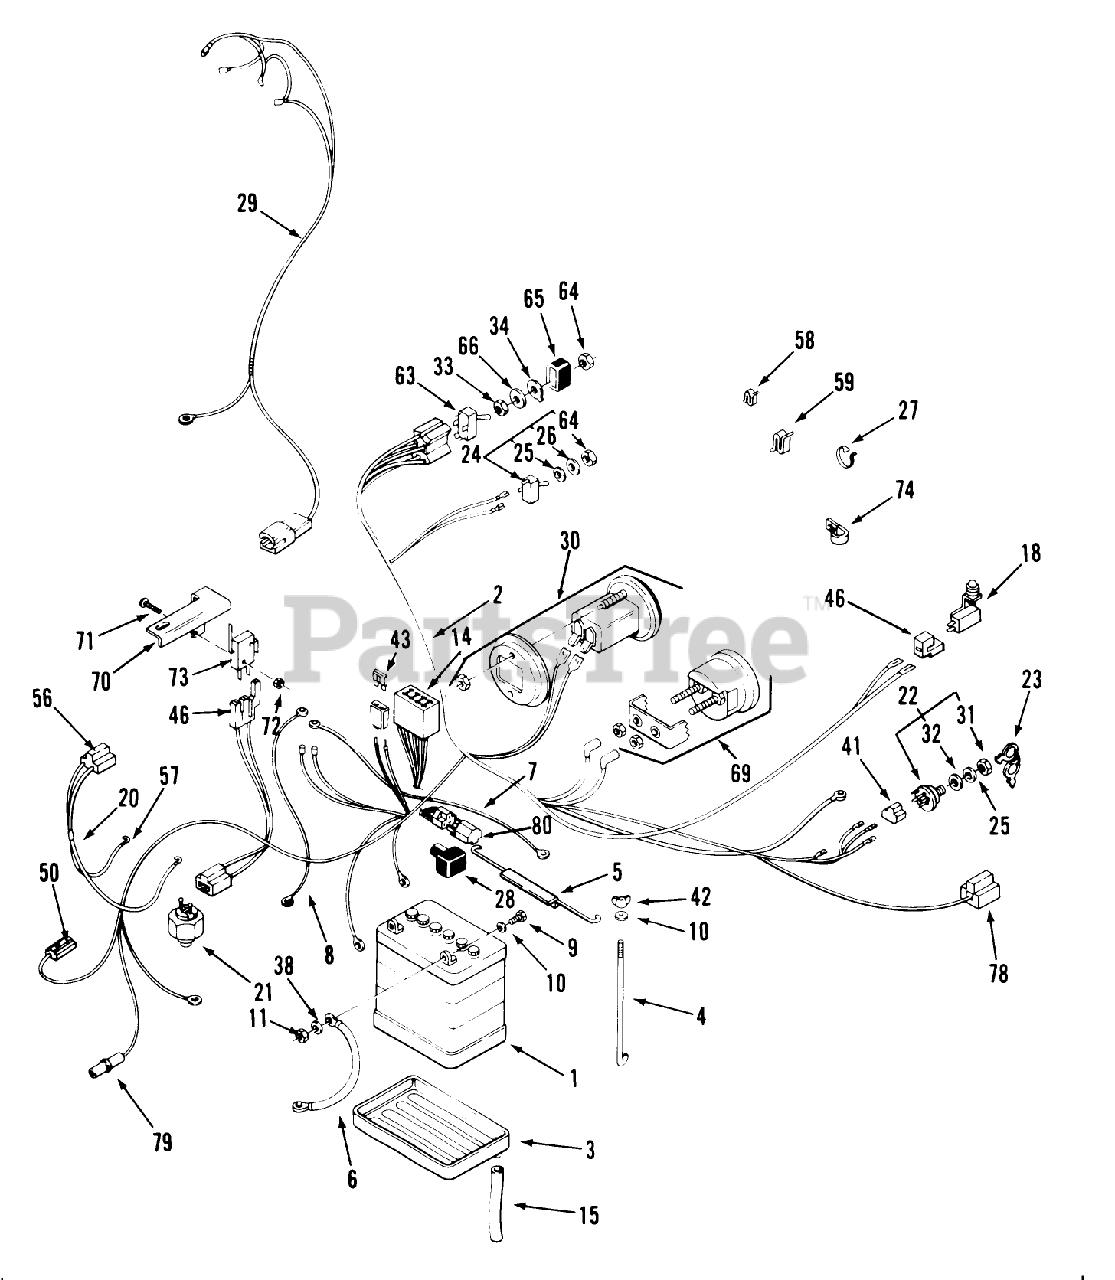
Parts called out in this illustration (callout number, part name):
3	TRAY-BATTERY
5	ROD-BATTERY HOLD DWN
6	WIRE -BLACK
7	WIRE - 14" BLACK
15	TUBE-BATTERY DRAIN
20	ASSY WIRING HARNESS
21	SWITCH (N.C.-TRANS)
24	SWITCH-LIGHTS
26	Washer
30	GAUGE-HOURMETER
34	TAB-WASHER
43	FUSE-BLADE, 15 AMP
46	CONNECTOR BODY
50	CONNECTOR BODY ELECT
56	CONNECTOR BODY *B
57	TERMINAL-TAB RCPT
58	CLIP
63	SWITCH-TOGGLE DPDT
64	*DISC**
65	COVER-PTO SWITCH
66	WASHER-FLAT
73	SWITCH
74	CLAMP
78	CONNECTOR 5 WAY
80	RELAY
